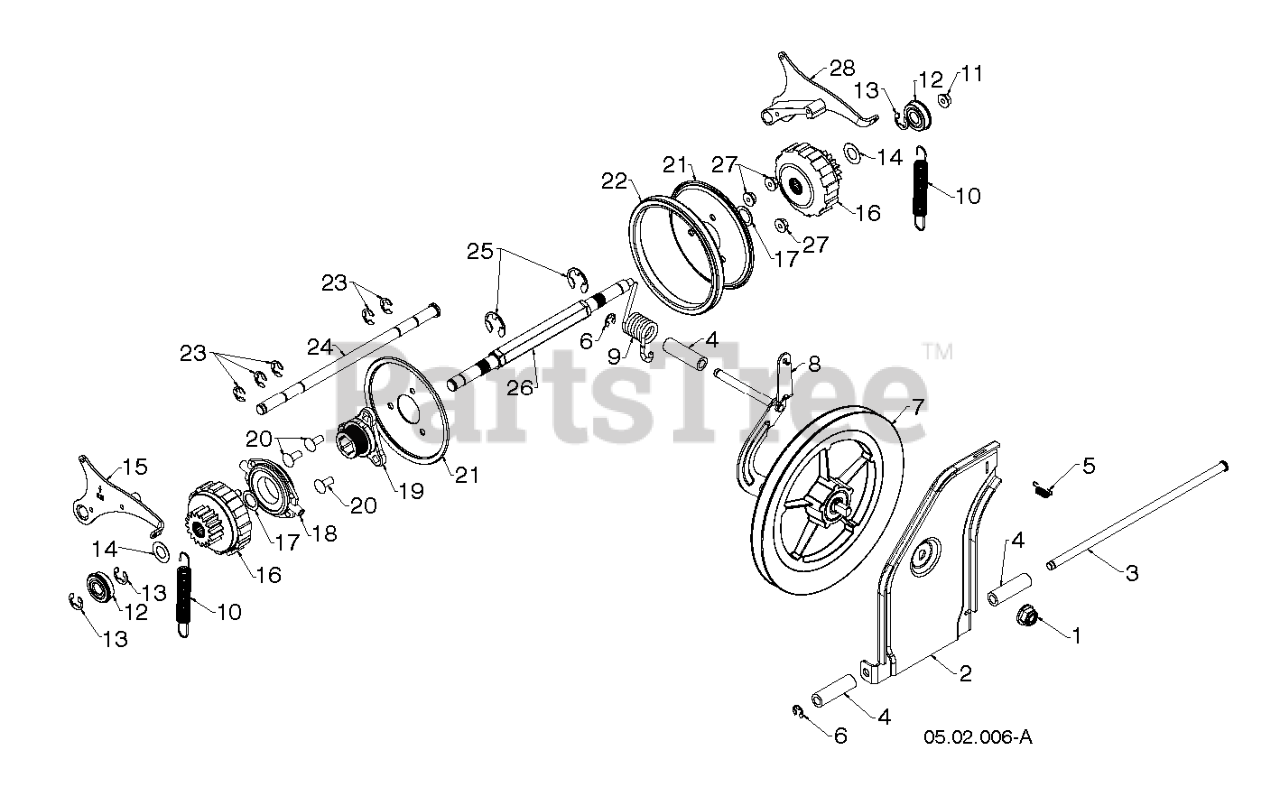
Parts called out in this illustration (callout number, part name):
1	NUT 1/2-13 HEX FLANGE NYLOK CL
2	PLATE.SWING.FRICTION PULLEY.47
3	ROD ROD,PIVOT, SWING PLATE ROD
4	SPACER YOKE, TORSION SPRING
5	SPRING LATCH
6	RETAINER RING E-RING CLEAR ZI
7	PULLEY.FRICTION.DISC.COMBO
8	BRACKET.YOKE.ASSEMBLY.479
9	SPRING TORSION DRIVE
10	SPRING EXTENSION PS
11	NUT.HEX.FLANGE.LOCK.5/16-18
12	BEARING 9/16 ID. SNR
13	RING.RETAINING.1622-2RSNR.CLER
14	WASHER FLAT.637IDX1.00ODX21GA
15	PAWL.ASM.RH.SNOW
16	GEAR.ASM.PLANETARY
17	WASHER FLAT.59IDX1.065ODX25GA
18	BEARING HOUSING ASSY TRUNNION
19	HUB.RUBBER.WHEEL
20	RHSNB 5/16-18 X 3/4 GR5 BLK ZN
21	PLATE.RUBBER.WHEEL.BLACK
22	RING RUBBER
23	CLIP E-RING_.500 SHAFT
24	ROD ROD, PAWL ROD
26	SHAFT SHAFT, PWR STR SHAFT
27	NUT.HEX.FLANGE.LOCK.5/16-18
28	PAWL.ASM.LH.SNOW
